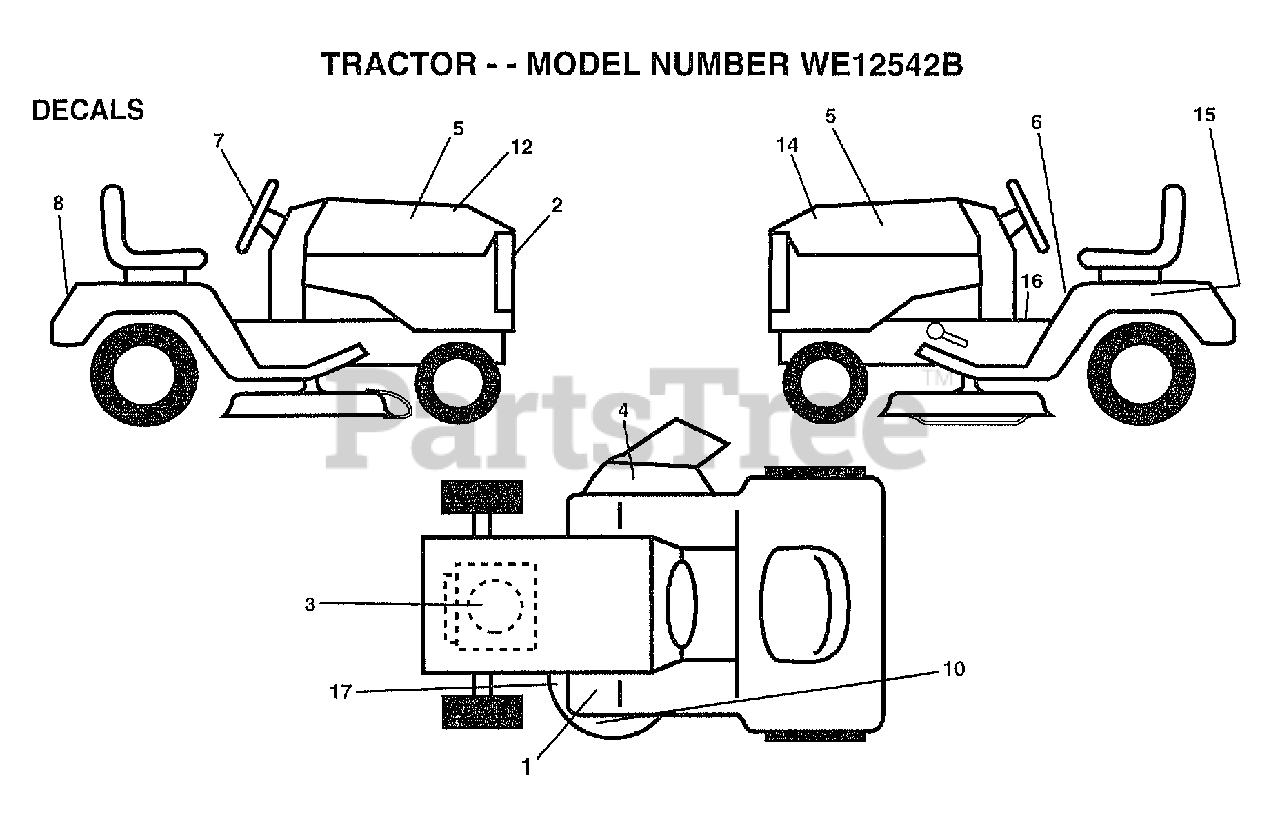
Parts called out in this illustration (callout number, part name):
1	DECAL, CLUTCH/BRAKE ENGLISH
2	DECAL, GRILLE LENS
3	DECAL, HP ENGINE
4	"DECAL, WARNING"
5	DECA, PNL SD
6	DECAL.CAUT.ENG/FR
7	DECAL, INS STRG WH
8	DECAL.FENDER.LOGO
10	DECAL, DECK GRASSEATER
12	DECAL.HOOD.RH.
14	DECAL.HOOD.LH
15	DECAL.BATRY.3-3908
16	"DECAL.OPER,SDL"
17	"DECAL-SCHEM,BELT"
